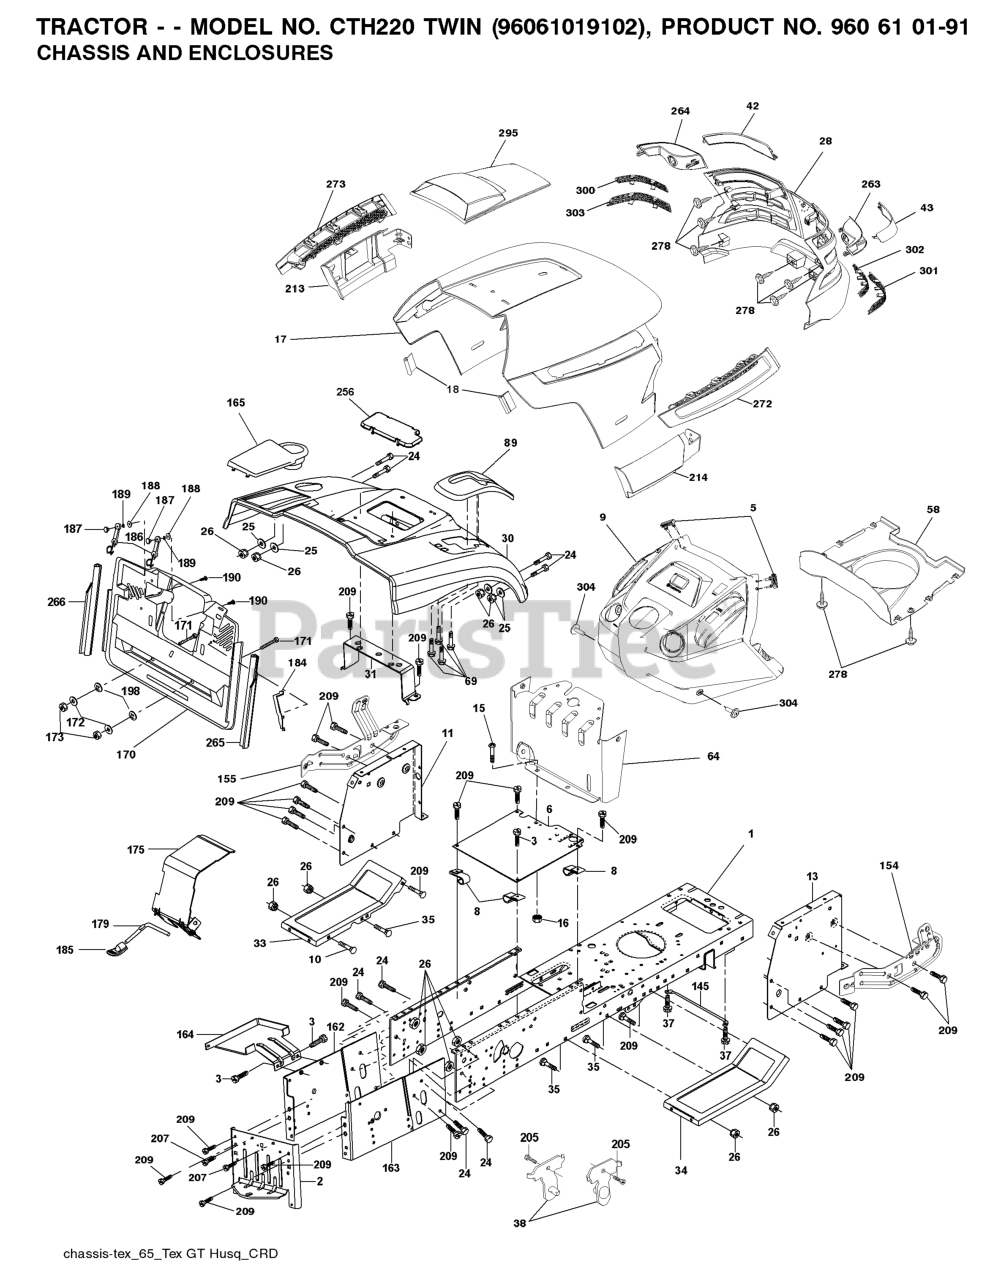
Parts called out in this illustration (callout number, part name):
2	DRAWBAR
3	SCREW 3/8-16X3/4
5	BUMPER DASH
6	PLATE
8	CLIP,INSULATOR
10	BOLT D
11	PANEL DASH LH
13	PANEL DASH RH
15	Screw, Machine, Truss Head 5/16-18 UNC x 3/4
16	NUT
17	HOOD
18	BUMPER.HOOD.TEX.HUSQVARNA
25	WASHER
26	NUT
28	GRILL.ASM.HUSQ.TG/CRD.W/TRIM
30	CONSOLE.CRD.AUTO.GRY
31	BRACKET SUPPORT FENDER
33	FOOTREST PNT LH
34	FOOTREST PNT RH
37	Screw 5/16-18 x 1/2 Hex, Self Tapping 5/16-18 x 1/2
38	BRACKET ASM PIVOT MOWER REAR
42	LENS.LH.TEX.GT.HUSQ.CL
43	LENS.RH.TEX.GT.HUSQ.CL
58	AIR.DUCT.HOOD.TEX.GT.HUSQ
69	SCREW.HI-LO.CONSOLE
89	CONSOLE.CRD.AUTO.GREY.2005
145	ROD.PIVOT.HOOD
162	BRACKET
163	BRACKET EXTEN CHASSIS RH CRD
165	RP.COVER.BATTERY.CRD.GREY
172	WASHER
175	DOOR TRAP
179	ROD PIVOT FBI
184	BRACKET.ACTUATOR.BAGGER.SRD
186	LATCH ASSY
187	WELDNUT
189	LOCKWASHER #10
190	SCREW
207	SCREW, 5/16-18 X 1/2
209	SCREW, 3/8-16X3/4
213	SKIRT.HOOD.SIDE.HUSQ.LH.GREY
214	SKIRT.HOOD.SIDE.HUSQ.RH.GREY
256	COVER FENDER CRD
263	BEZEL.RH.TEX.GT.HUSQ
264	BEZEL.LH.TEX.GT.HUSQ
265	SEALING
266	SEALING
272	VENT.SIDE.HOOD.HUSQ.RH.GREY
273	VENT.SIDE.HOOD.HUSQ.LH.GRAY
278	SCREW
295	VENT.ASM.TORPHD.HUSQGT.LOGO.CL
300	INSERT.HEX.GRILL.HUSQ.
301	INSERT.HEX.GRILL.HUSQ.GREY
302	INSERT.HEX.GRILL.HUSQ.
303	INSERT.HEX.GRILL.HUSQ.
304	SCREW 14-20 X 5/8
